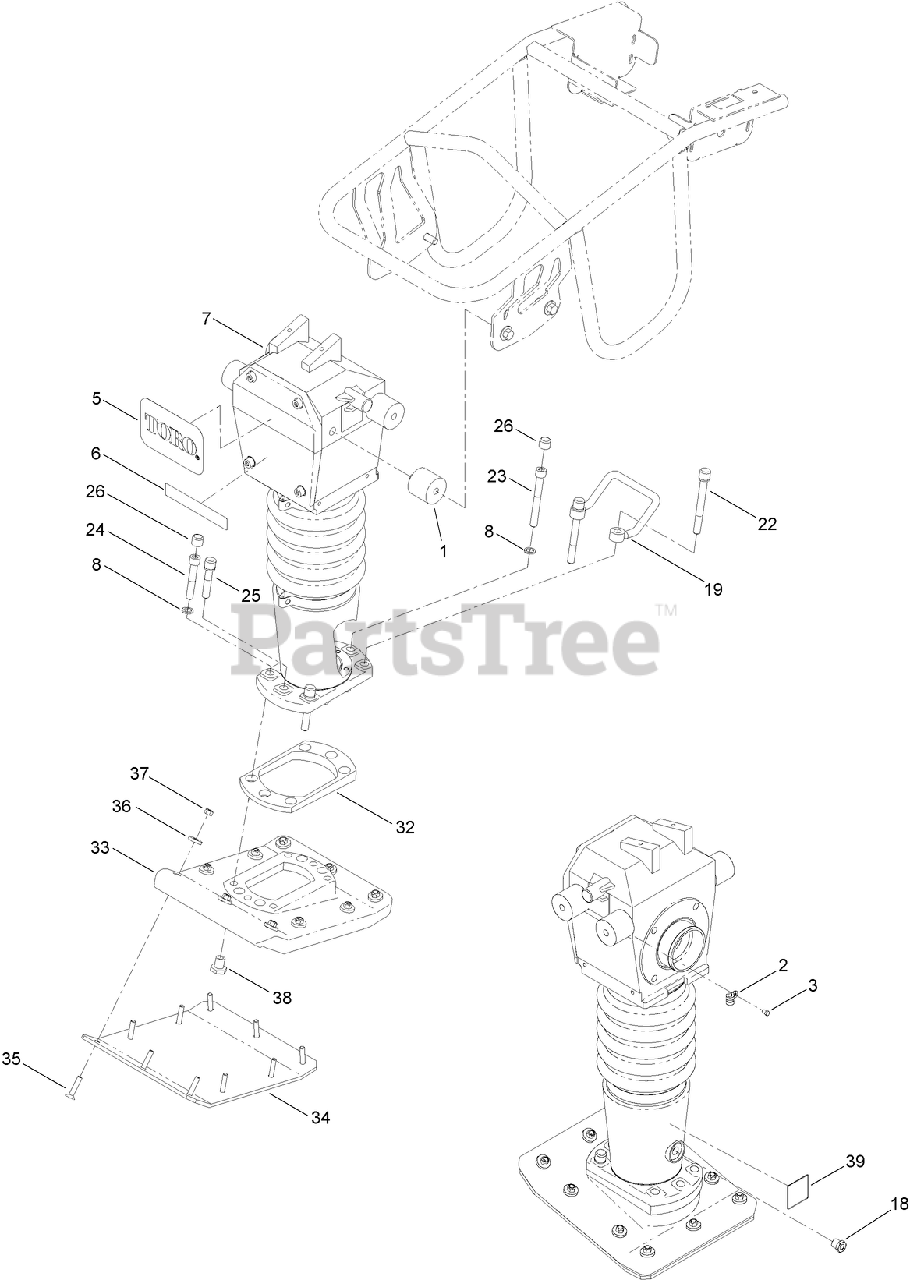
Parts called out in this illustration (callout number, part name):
1	MOUNT-SHOCK
2	CLAMP
3	SCREW-HH
5	DECAL
6	DECAL
7	RAMMER ASM
8	WASHER-LOCK
18	PLUG-SIGHT, OIL
19	GRIP-LIFT
22	SCREW-HSH
23	SCREW-HSH
24	SCREW-HSH
25	SCREW-HSH
26	CAP-PLASTIC
32	PLATE-SPACER, SHOE
33	SHOE-PLASTIC, MEDIUM/HEAVY
34	PLATE-SHOE
35	SCREW-HSFH
36	WASHER-FLAT
37	NUT-LOCK, NI
38	INSERT-SHOE
39	DECAL-OIL LEVEL
